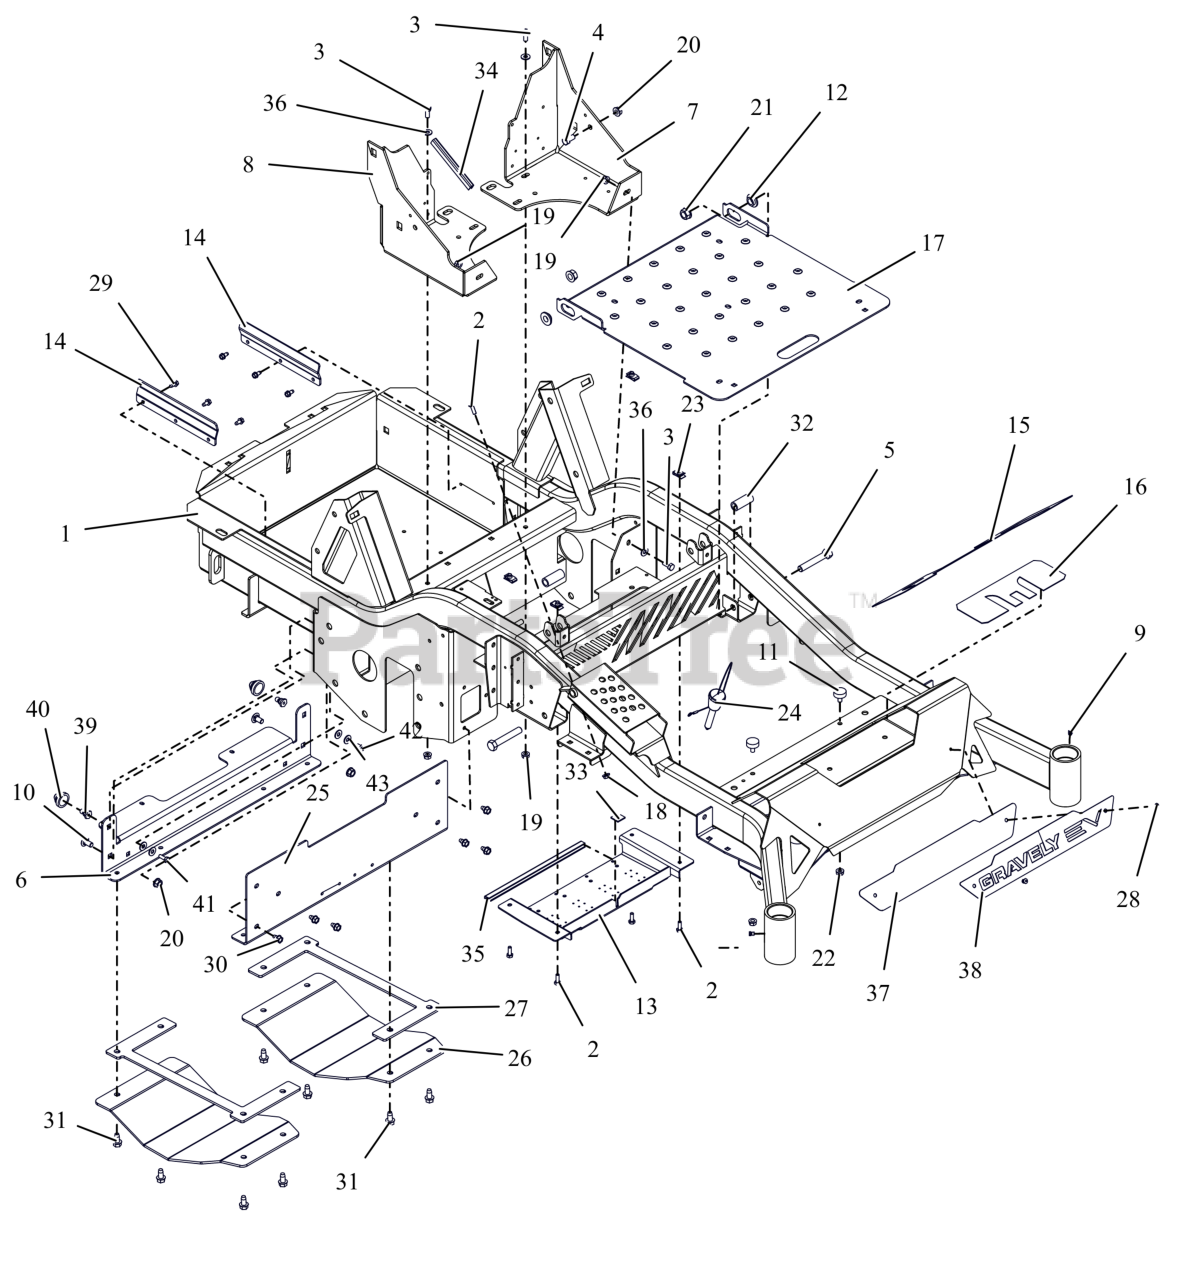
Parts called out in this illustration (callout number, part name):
1	KIT,EV FRAME(SM)W/DECALS-G
2	BLT, HEX .25-20X.75 G5 ZCC
3	BLT,HEX .31-18X.75 G5 ZCC
4	BLT,HEX .38-16X.75 G5 ZCC
5	BLT, HEX .50-13X3.00 G5 ZCC
6	BRKT, SKID PLATE MTG. (RED)
7	BRKT, SUPPORT ROPS -LH (RED)
8	BRKT, SUPPORT ROPS-RH (RED)
9	FTG, .25-28 FLUSH MNT GREASE
10	BLT, RHSSN .38-16X.75 G5 ZCC
11	BUMPER, RUBBER
12	BSHG-FLG .515X.750X.310X1.120
13	COVER, BOTTOM ACCESS -OPEN (RED)
14	DEFLECTOR, BATTERY -EV (RED)
15	GRIP, FRONT
16	GRIP, TAPE FRONT
17	KIT,ACCESS PANEL W/DECALS-RED
18	NUT-LK-CTR-FLG .25-20 ZC120
19	NUT,LK-CTR-FLG .31-18 GF ZCC
20	NUT-LK-CTR-FLG .375-16 GF ZCC
21	NUT-LK-CTR-FLG .500-13 GG ZCC
22	NUT,SPNLK-FLG .31-18 G5 ZCC
23	NUT-RTNR .25-20X.56
24	PIN- MAGNETIC .50X2.70
25	PLATE, FRONT FRAME (RED)
26	PLATE, SKID (BLACK)
27	PLATE, SKID TENSION (BLACK)
28	RIVET, .1875 AL/AL .126-.250
29	SCR-TAP .25-20X.50 HWH ZCC
30	SCR,TAP .312-18X.50 HWH TR ZCC
31	SCR,TAP .375-16X.75 HWH TR ZCC
32	SPACER, .515X.75X1.83
34	STRIP, COWL
35	STRIP, COWL
36	WSHR, FLT .312X.734X.065 ZCC
37	PLATE, BACK - GRAVELY (BLACK)
38	PLATE, LOGO - GRAVELY EV (RED)
39	STUD, BALL FEMALE .250-20 THREAD
40	COUPLING, RUBBER PUSH-IN
41	BLT, HEX .25-20X.75 G5 ZCC
42	BLT,HEX .25-20X.50 G5 ZCC
43	WSHR, FLT .312X.734X.065 ZCC
